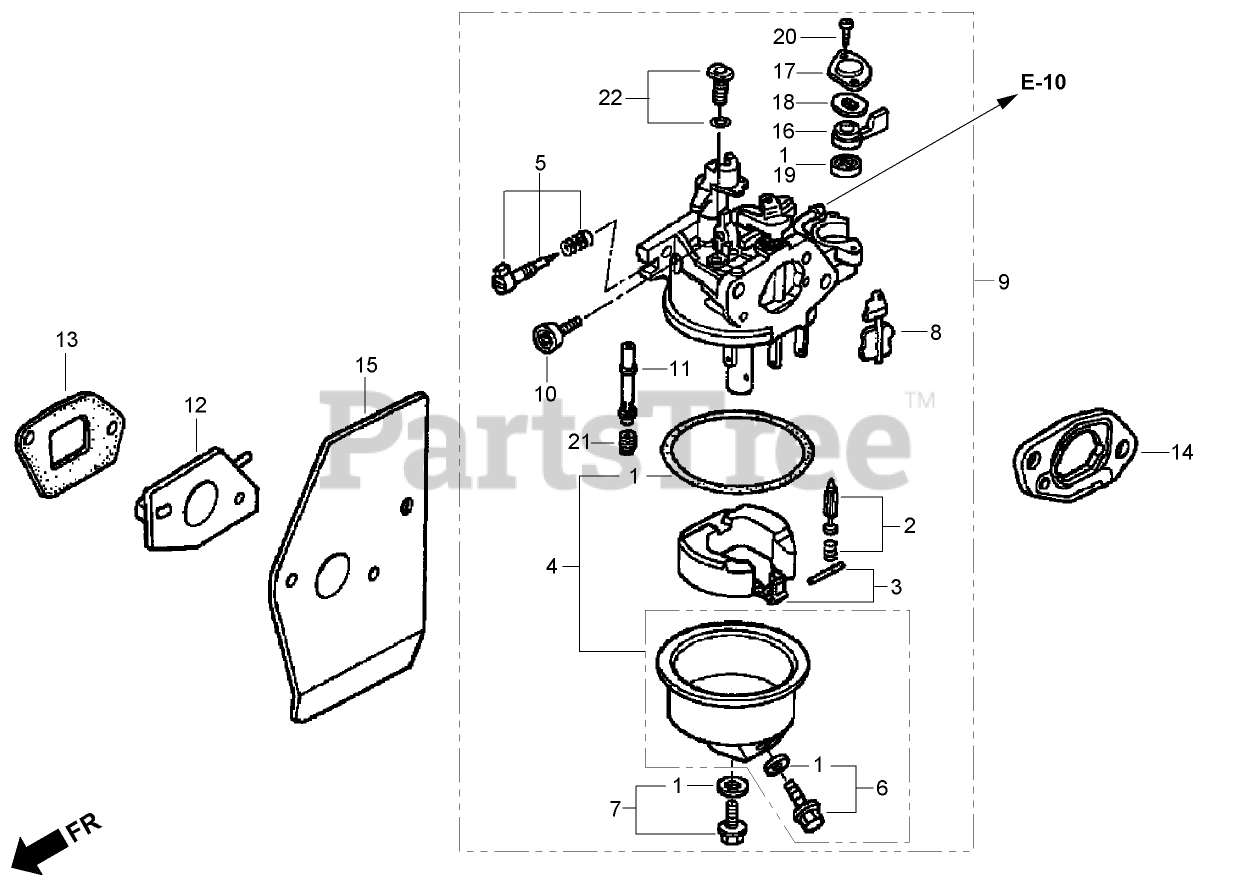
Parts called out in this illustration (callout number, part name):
1	GASKET SET
2	FLOAT VALVE SET
3	Float Set
3	FLOAT SET (CARBURETOR NO. BE66N A)
4	FLOAT CHAMBER SET
5	PILOT SCREW SET
6	DRAIN SCREW SET
7	SCREW SET
8	Choke Set
8	CHOKE SET
9	CARBURETOR ASM (BE66J A) (Engine Serial No. Up To 1001679)
9	CARBURETOR ASM (B E66 N A)
10	SCREW- STOP, THROTTLE
11	NOZZLE-MAIN (CARBURETOR NO. BE66J A)
11	NOZZLE-MAIN
12	Insulator-Carburetor
13	Gasket-Insulator
14	Spacer-Carburetor
15	Gasket-Carburetor
16	LEVER-PETCOCK
17	PLATE-SETTING, LEVER
18	SPRING-LEVER, PETCOCK
19	GASKET-PETCOCK
20	SCREW-PAN (3X6)
21	JET-MAIN (No. 60)
21	JET-MAIN (No. 62)
21	JET-MAIN (No. 65)
21	JET-MAIN (No. 68) (CARBURETOR NO. BE66N A)
22	PILOT JET SET (No. 35)
